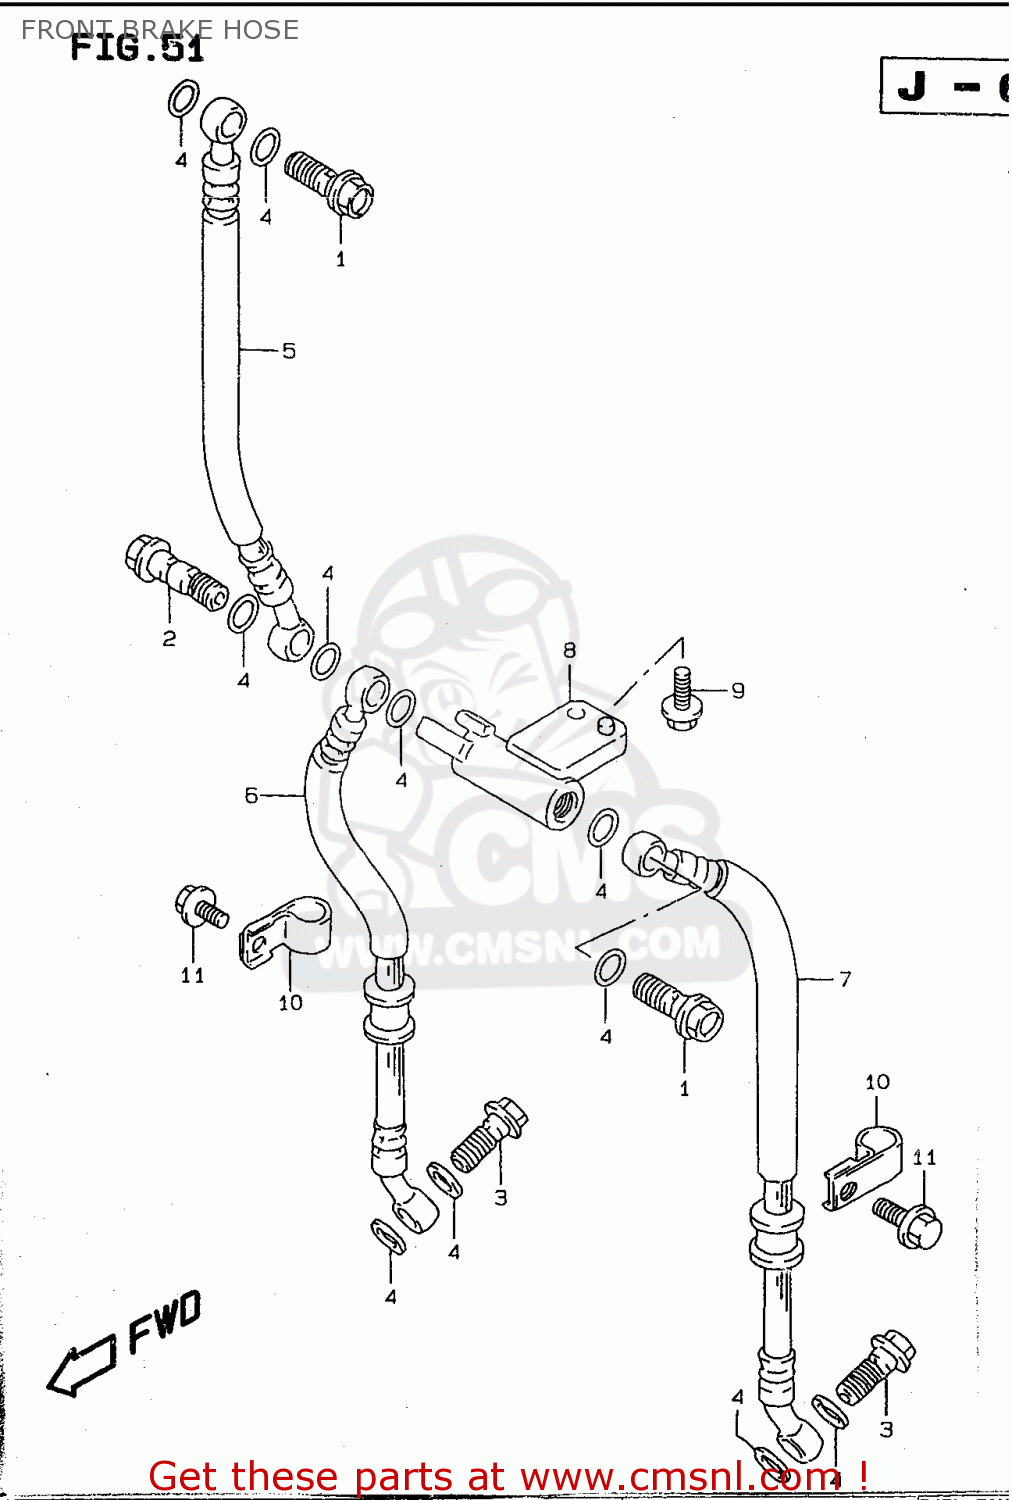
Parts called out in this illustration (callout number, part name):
1	BOLT UNION
2	BOLT UNION
3	BOLT UNION
4	WASHER(10X15X1.5)
5	HOSE,FR BRAKE NO.1
6	HOSE,FR BRAKE NO.2,R
7	HOSE,FR BRAKE NO.2,L
8	JOINT,BRAKE HOSE
9	BOLT
10	CLAMP,FR BRAKE HOSE NO.2
11	BOLT
